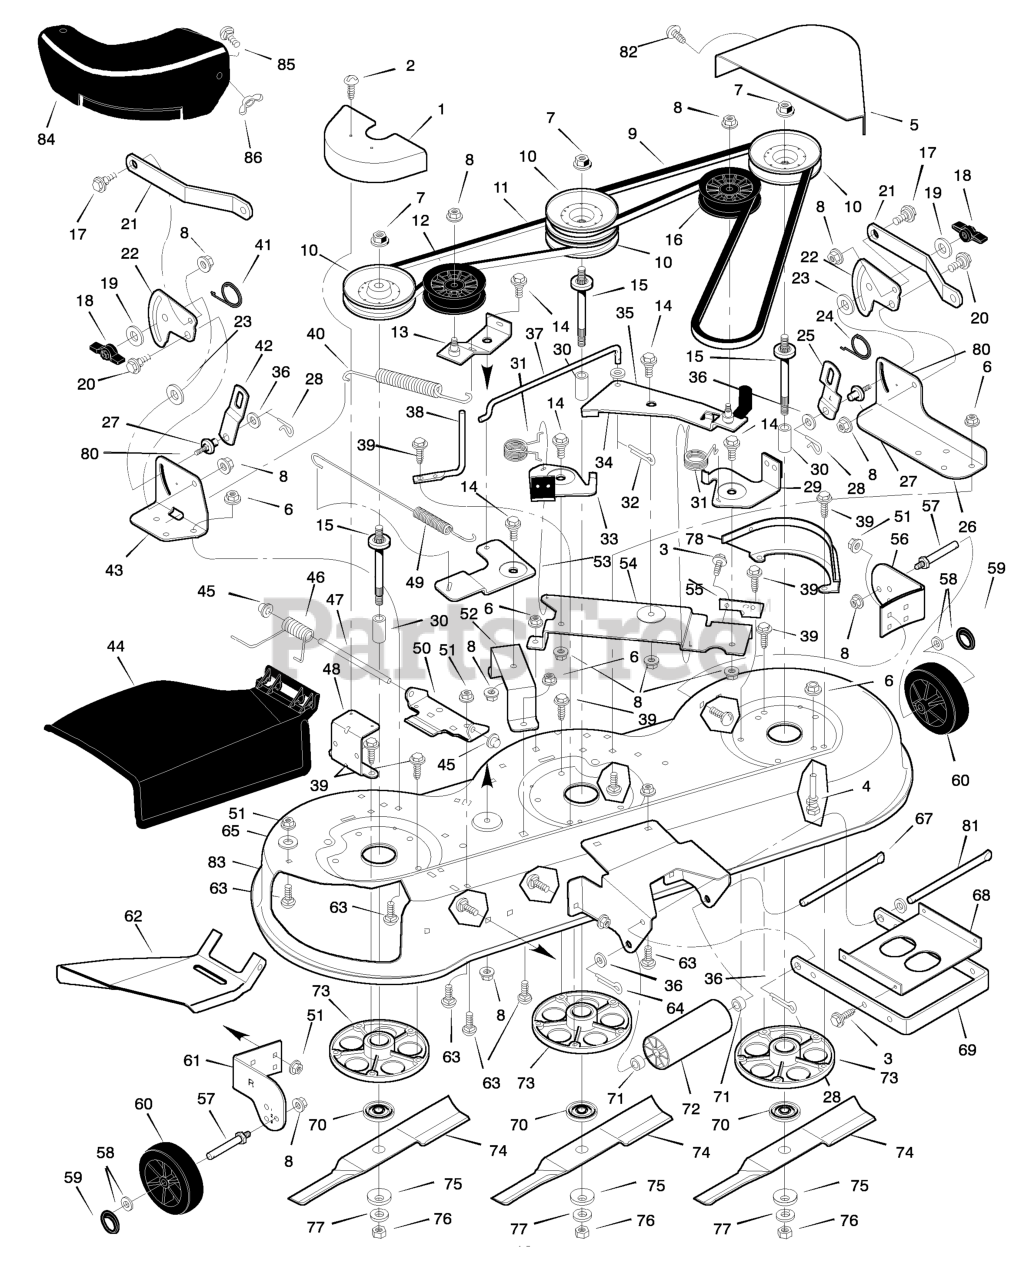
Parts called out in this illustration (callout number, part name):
1	Cover, Right Pulley
2	Screw
4	Guide, Belt
5	Cover, Left Pulley
6	Nut, Hex
7	Nut, Flange
8	Nut, Flange
9	Belt, Primary
10	Pulley
11	Belt, Secondary
12	Pulley, Idler
13	Arm, Idler
14	Bolt, Shoulder
15	Shaft, Splined
16	Pulley, Idler
17	Bolt, Shoulder
18	Knob
20	Bolt, Shoulder
21	Bracket, Rear Suspension
22	Plate, Suspension
23	Pad, Friction
25	Link, Left Lift
26	Bracket, Left Lift
27	Pin, Hanger
28	Pin, Hair
29	Brake Assembly, Left
32	Pin, Cotter
33	Brake Assembly, Right
34	Washer
35	Idler, Arm
37	Link, Bell Crank
38	Guide, Belt
39	Screw
40	Spring, Extension
41	Spring, Torsion
42	Link, Lift
43	Bracket, Right Lift
44	Deflector, Chute
45	Push On Cap
46	Spring, Torsion
47	Rod, Deflector
48	Bracket, Cover
49	Spring, Extension
50	Bracket, Hinge
51	Nut, Flange
52	Bracket, Bell Crank
53	Crank, Bell
54	Plate, Brake Arm
55	Bracket, Brake Plate
56	Bracket, Left Gauge Wheel
57	BOLT, Gauge Wheel
59	Ring, Locking
60	Wheel, Gauge
61	Bracket, Right Gauge Wheel
62	Deflector, Inside
63	Bolt, Carriage
64	Pin, Cotter
66	Bracket, Front Deck
67	Rod, Hanger
68	Stiffener
69	Bracket, Suspension
70	Adapter, Blade
73	Housing, Jackshaft
75	Washer, Belleville
78	Bracket, Pulley Cover
81	Rod, Hanger
83	Housing, Blade
84	Cover, Discharge
85	Bolt
86	Wingnut
